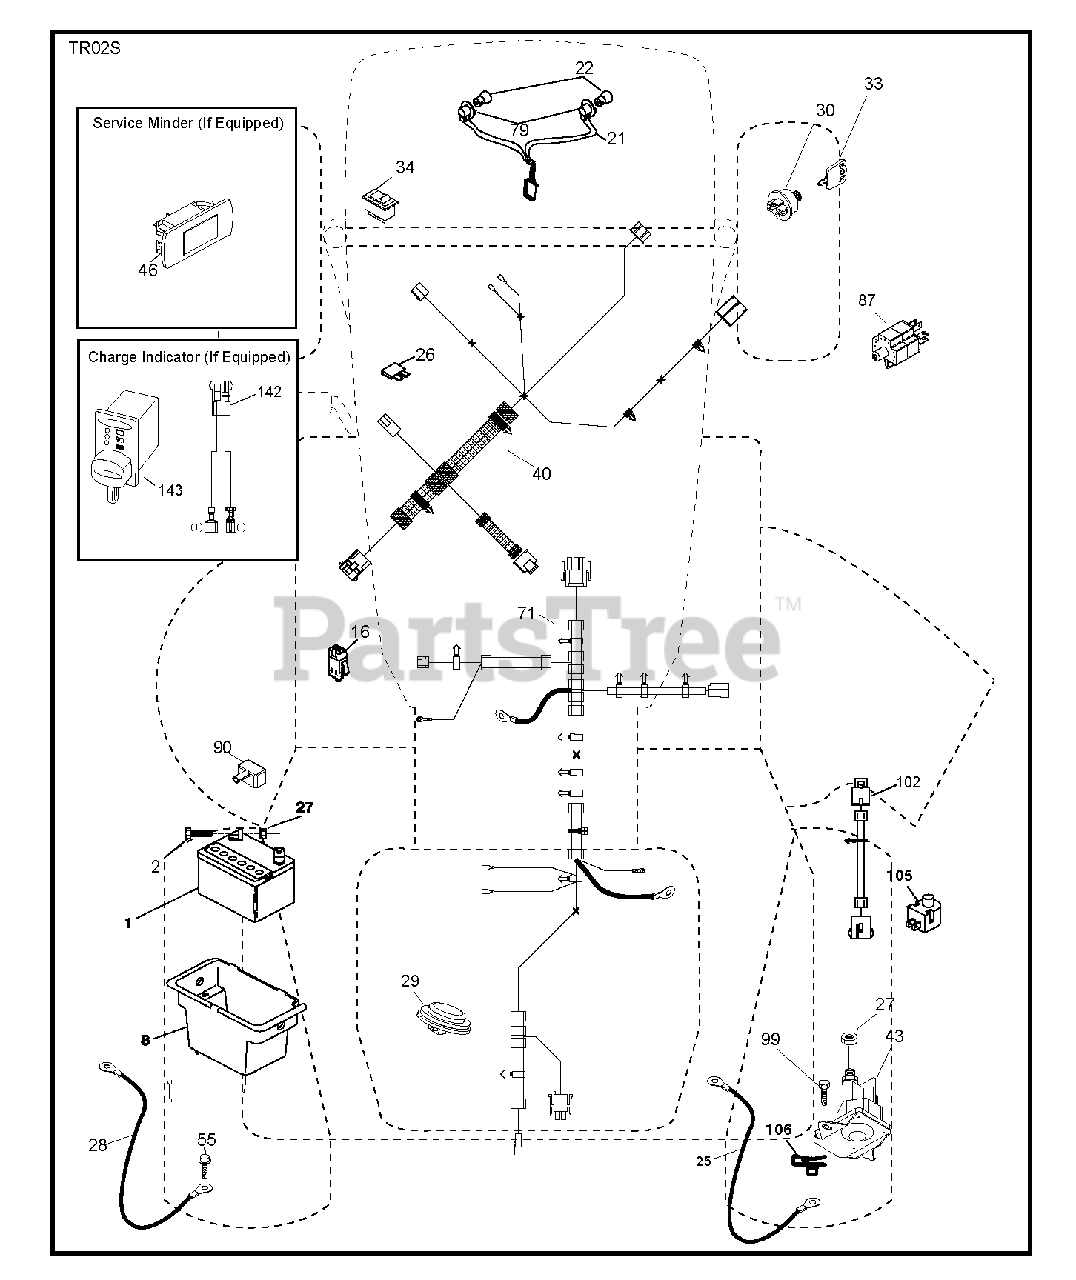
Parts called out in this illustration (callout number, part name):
1	REPL BY 532 12 38-99
2	BOLT.HEX.1/4.X.3/4.DICHROMATE
8	BOX.BATTERY.MNT.REAR.L
16	SWITCH INTERLOOK PUSH-IN
21	HARNESS.LIGHT W/4152J BULBS
22	LIGHTBULB
25	CABLE.BATT.RED.8GA.17
26	FUSE 20AMP
27	NUT
28	CABLE.GROUND.REAR.BATTERY.8G
29	SWITCH.SEAT.DELTA.OPC.
30	SWITCH.IGN.DELTA.W.LGH.ROS
33	KEY.CHAIN.BLISTER.PACK.GEN.USA
34	SWITCH LT
40	HARNESS.DASH.TEX.CC.SQ.RDYSTR
43	SOLENOID.W/BRASS.PLUNGER
55	SCREW 5/16"
71	HARNESS.CHASSIS.RRBATT.RDYSTRT
79	BULB HOLDER ASM.
87	SWITCH.INTRLCK.CLUTCH.
90	COVER.TERMINAL.BATTERY
99	SCREW HEXWSHR 1/4-20X3/4
102	HARNESS PIGTAIL PCH TEX ROS
105	REVERSE SWITCH
106	1/4-20 U NUT
